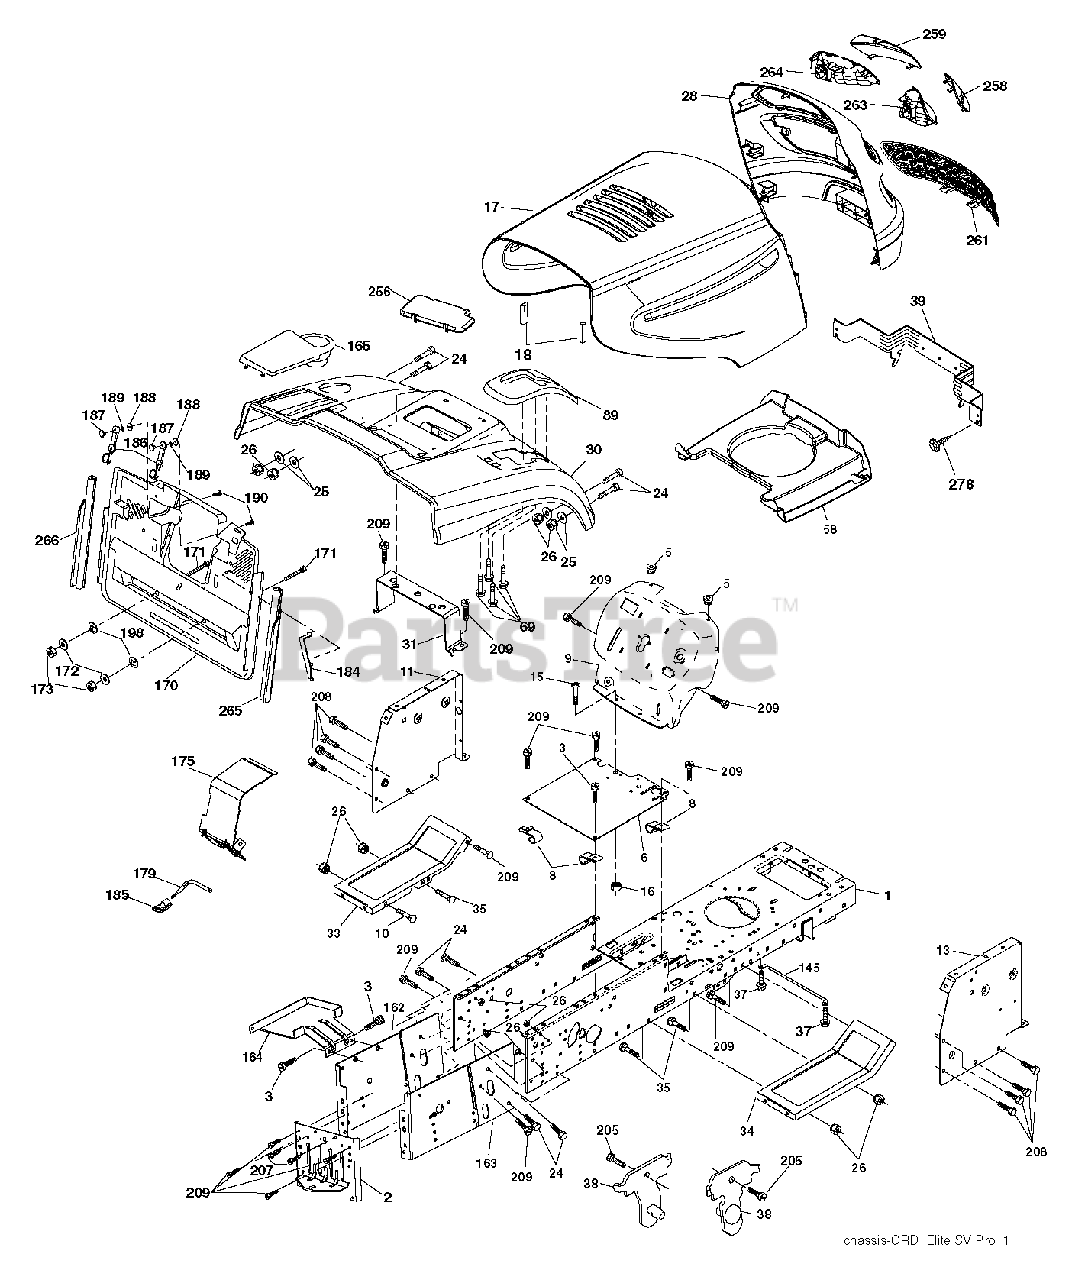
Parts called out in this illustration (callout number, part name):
1	CHASSIS
3	SCREW 3/8-16X3/4
5	BUMPER.RUBBER.HOOD
8	CLIP,INSULATOR
9	FENDER LT SH
10	BOLT D
11	PANEL.DASH.LH.LTX
13	PANEL.WELDMENT.DASH.R
16	NUT
17	HOOD.STEEL.ELITE.-SV.PRO.667
18	BUMPER.HOOD.LARGE.1.75"
25	WASHER
26	NUT
30	FENDER.PNT.CRD.MS667
31	BRACKET SUPPORT FENDER
33	FOOTREST.PNT.LH.MS667
34	FOOTREST.PNT.RH.MS667
39	BRACKET PIVOT
69	SCREW.HI-LO.CONSOLE
89	CONSOLE.CRD.AUTO.BLACK
145	ROD.PIVOT.HOOD
164	SUPPORT
165	FENDER.PNT.CRD.
171	BOLT
172	WASHER
184	BRACKET.ACTUATOR.BAGGER.SRD
185	KNOB.BRAKE.PARKING.ROD
187	WELDNUT
207	SCREW, 5/16-18 X 1/2
208	SCREW 3/8-16X1/2
209	SCREW, 3/8-16X3/4
256	FENDER.PNT.CRD
258	Grille Lens, Pro RH Clear
263	BEZEL GRILL RH
264	BEZEL GRILL LH
278	SCREW.#10 X 0.750.BOS THREAD
